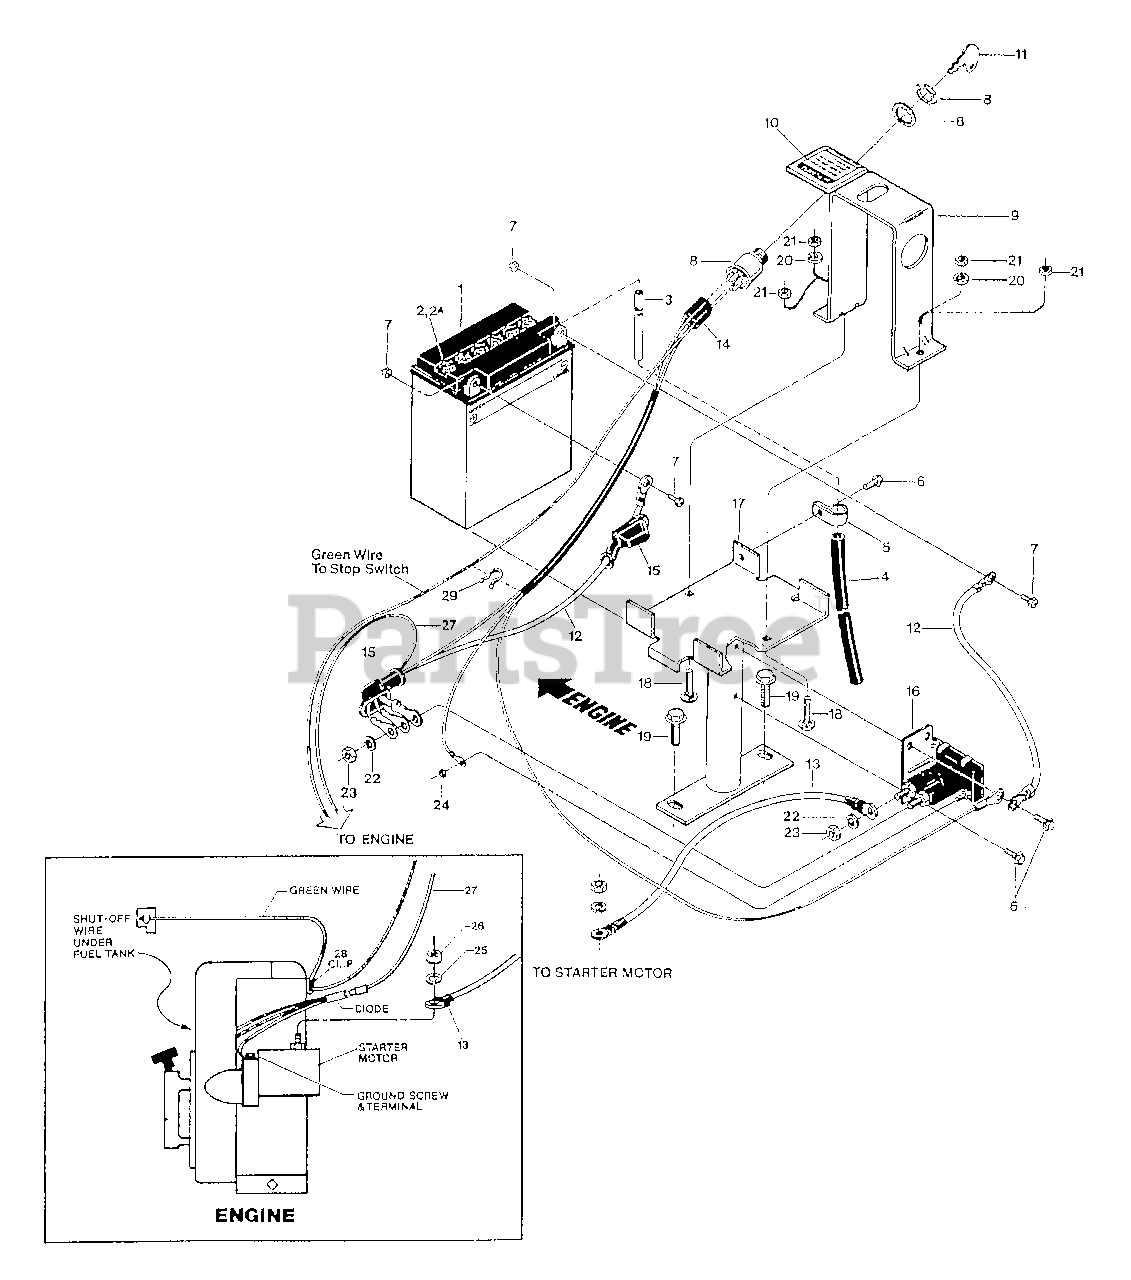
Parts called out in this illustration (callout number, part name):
1	BATTERY
2	CAP-YELLOW
2A	CAP-BATTERY WHITE (PONY)
3	TUBE-VENT BATTERY/HSE
4	TUBING-RUBBER
5	CLAMP
6	SCR-HWH 1/4-20 X .5 STH
7	HDW PKG-BATTERY TERMINAL
8	ASSM-KEYSWITCH ELEC TLR
9	ASSM-KEYSWITCH W/DECAL
10	DECAL-KEYSWITCH TILLER
11	KEYS-IGN T/BLAZER 1 PAIR
13	CABLE-BATTERY 12"
14	KIT-WIRE HARNESS ASSM (AVAILABLE AS COMPLETE ASSEMBLY ONLY)
15	BOOT-BATTERY CABLE
16	SOLENOID
17	BRKT-BATTERY OPC PNT
18	SCR-CARR 1/4-20X1.25
19	SCR-HFLK 5/16-18X1.00 ZP
20	WASHER-LK .25 ZP (USED ON EARLY UNITS ONLY)
21	NUT-HEX 1/4-20 ZP
21	NUT-HF/LK 1/4-20 ZP
22	WASHER-LK .312 ZP
23	NUT-HEX 5/16-24
24	NUT W/LKWASHER #10-32 ZP
25	LOCKWASHER
26	NUT
27	WIRE-RECHARGE 5&7 BRIGGS
28	CLIP-SPECIAL
29	TIE-TWIST LOCK
